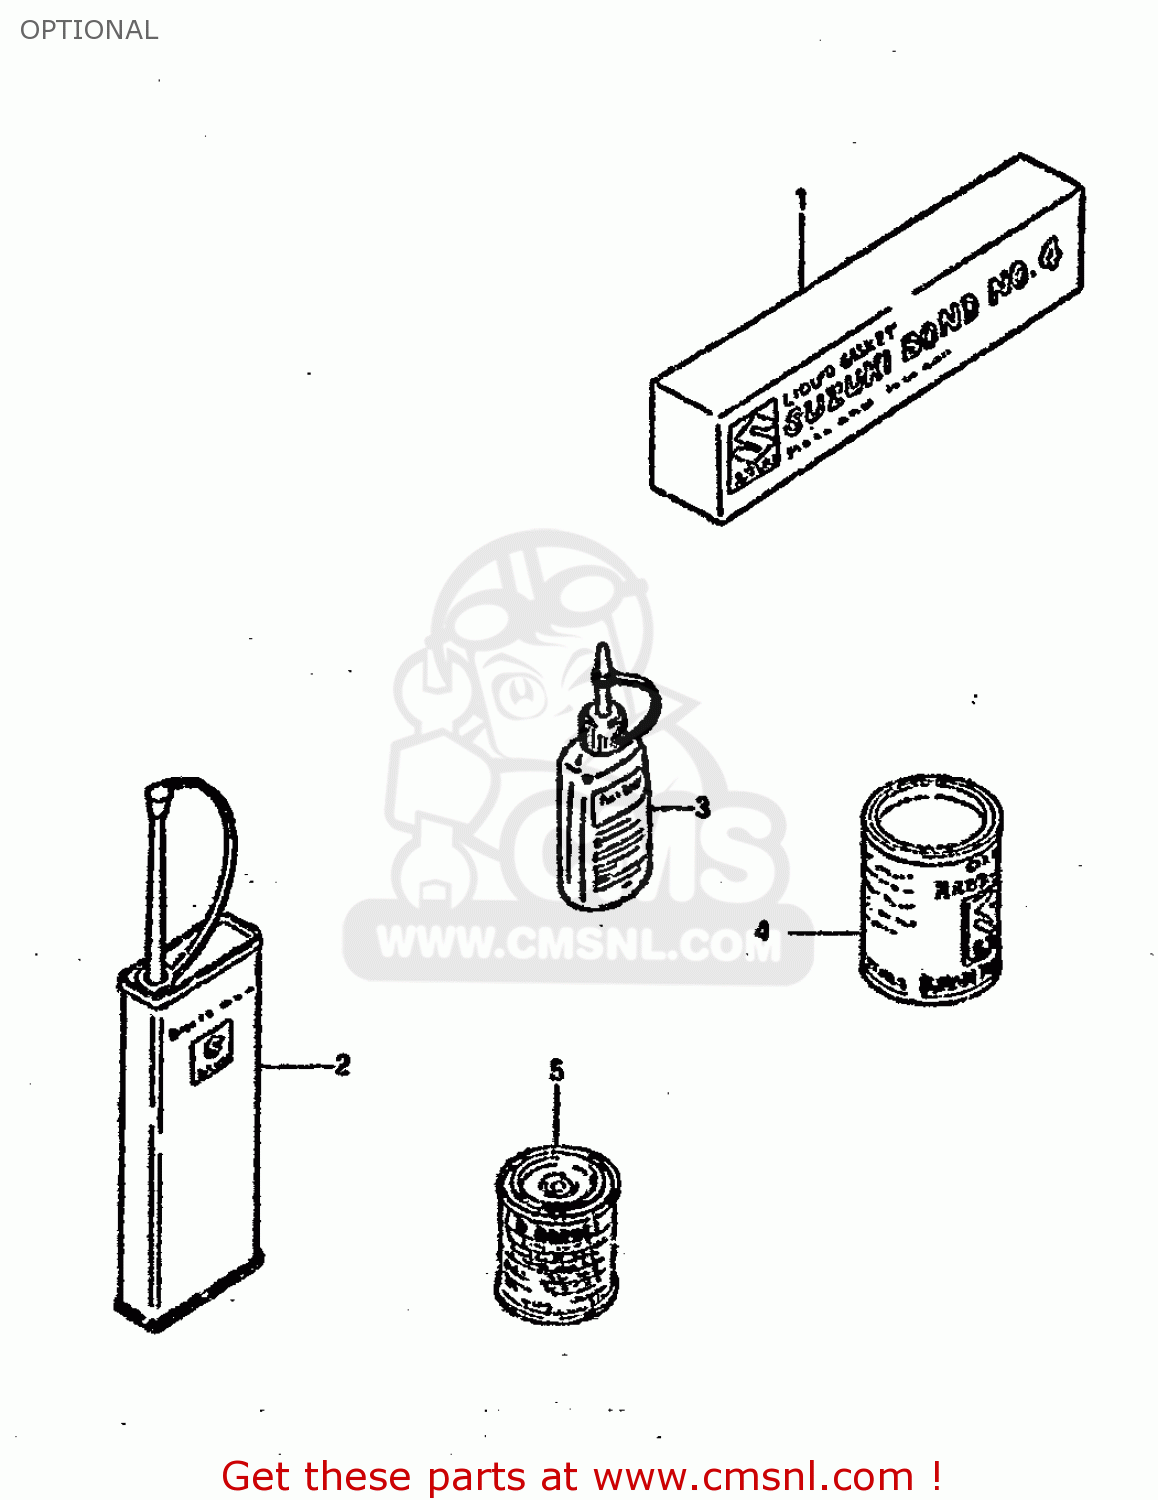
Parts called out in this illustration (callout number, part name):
1	BOND 1104
2	THREAD LOCK NO.1401 CLEAR 200G
3	THREAD LOCK NO
4	GREASE(C)EP2 LITHIUM 150G
5	PAINT,BLACK
